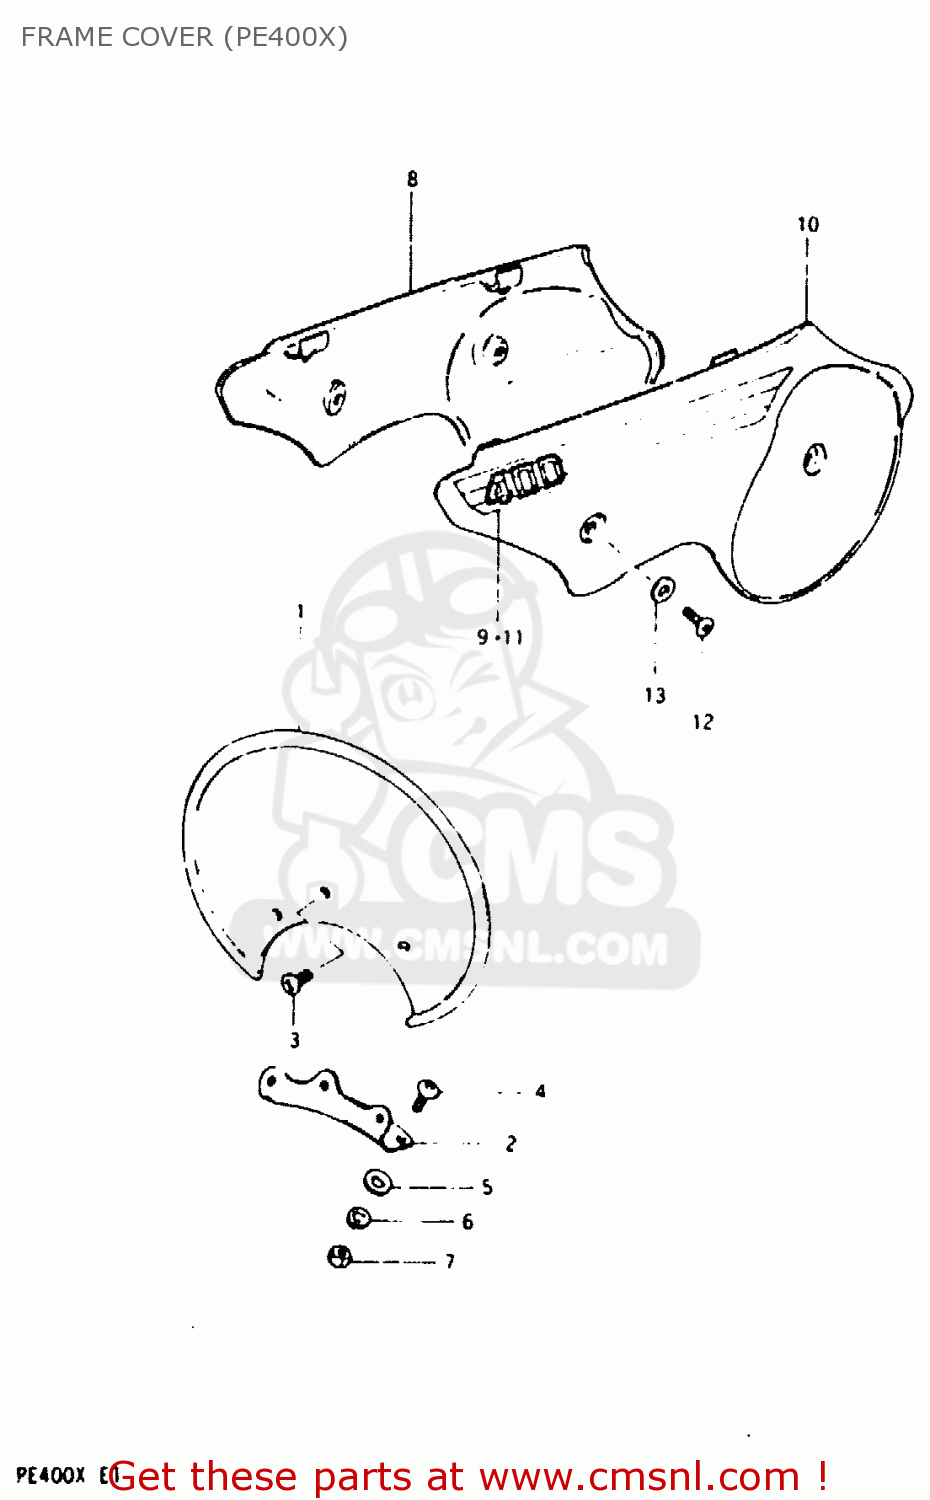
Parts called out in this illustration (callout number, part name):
1	PLATE,NUMBER,FRONT
2	BRACKET
3	SCREW
4	SCREW
5	WASHER
6	LOCK WASHER
7	NUT
8	COVER,FRAME,R(YELLOW)
9	TAPE,FRAME COVER
10	COVER,FRAME,L(YELLOW)
11	TAPE,FRAME COVER
12	SCREW
13	SPACER
